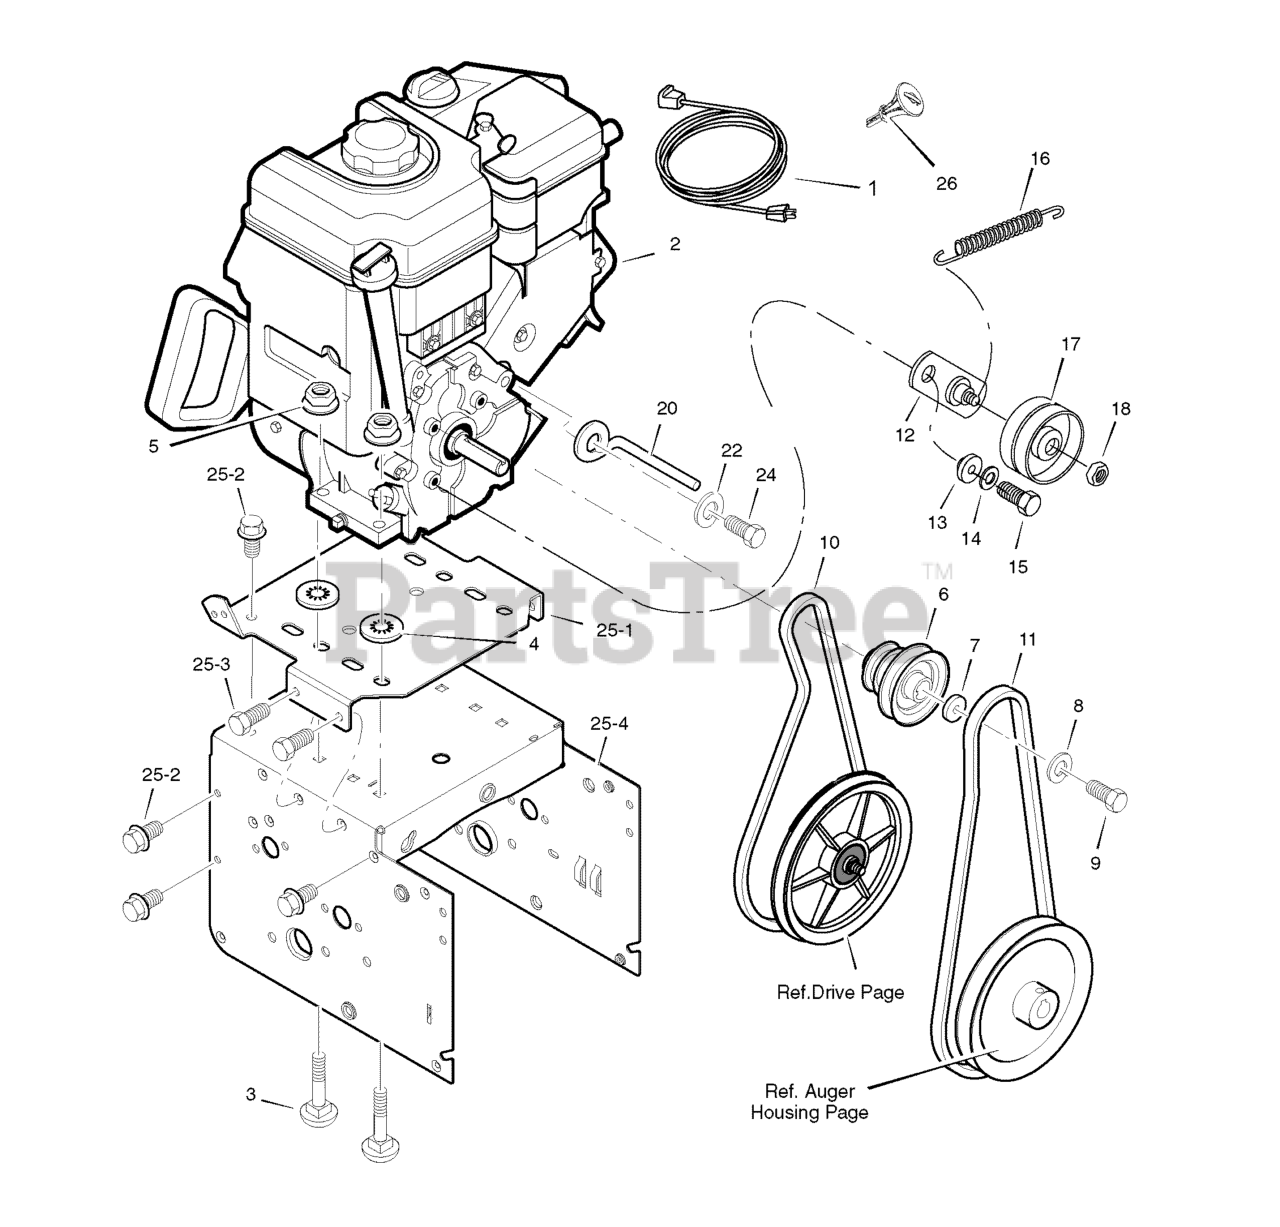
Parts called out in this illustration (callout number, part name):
1	CORD, STARTER
2	ENGINE
3	BOLT, CARRIAGE
4	RETAINER, PUSH
5	NUT
6	PULLEY, ENGINE
8	WASHER
10	BELT, DRIVE V 4L
11	BELT, AUGER V 3L
12	BRACKET ASSEMBLY, IDLER
13	BUSHING, IDLER BRACKET
14	WASHER, SPLIT
15	SCREW 5/16-24 X .75
16	SPRING, IDLER TRACTION DRIVE
17	PULLEY, IDLER
18	NUT, JAM 3/8-16
20	GUIDE, ROD BELT
22	WASHER
25	FRAME ASSEMBLY
25-1	PLATE, ENGINE
25-2	SCREW
26	KEY, BRIGGS ENGINE
